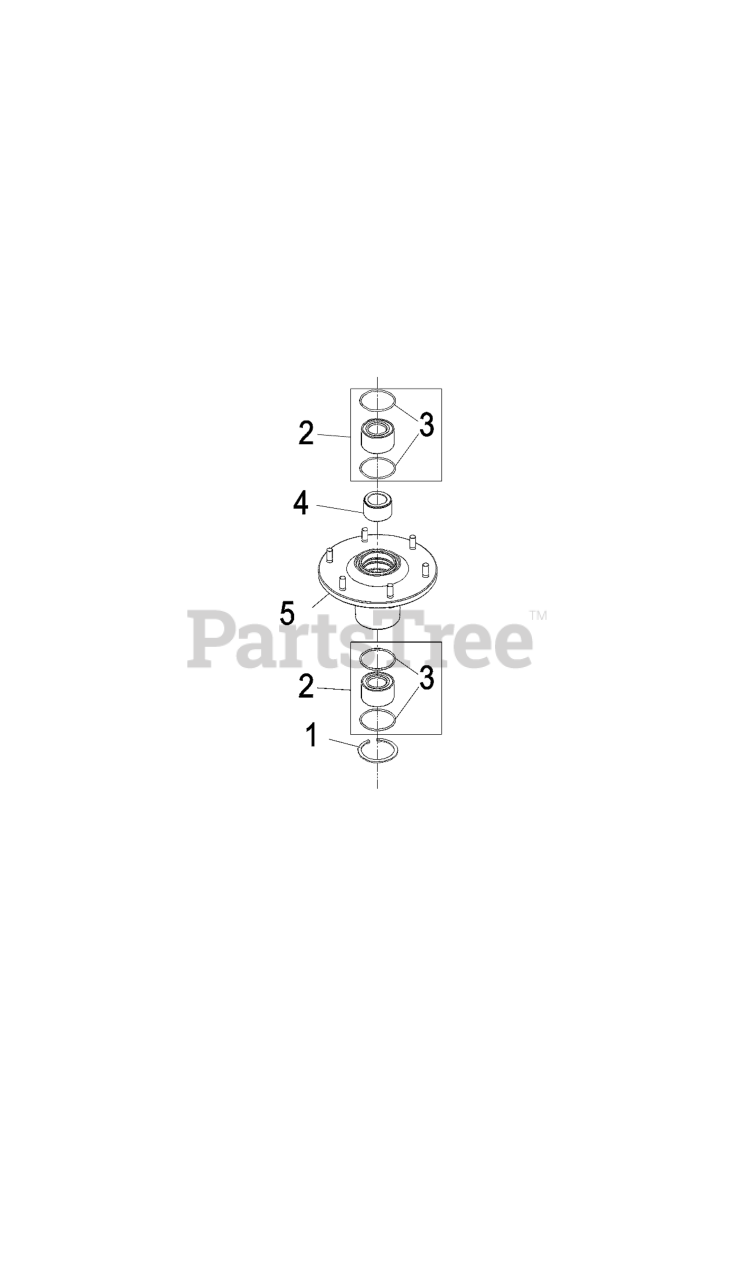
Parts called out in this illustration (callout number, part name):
1	RING-RETAINING
2	ASM, BEARING W/ORINGS
4	SPACER,BEARING
5	ASM,HOUSING W/STUDS
